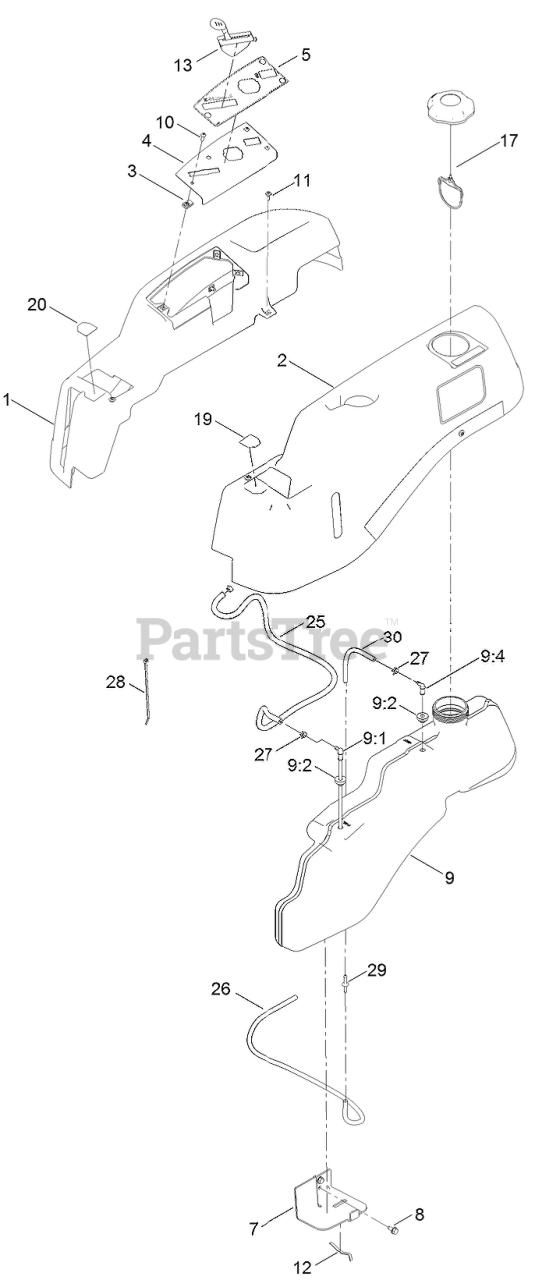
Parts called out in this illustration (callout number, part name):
1	POD-RH
4	PLATE-CONTROL
5	DECAL-PANEL, CONTROL
7	SUPPORT-TANK, FRONT
8	SCREW-HWHTF
9	FUEL TANK ASM
9:1	CONNECTOR-ELBOW, 90 DEG
9:2	BUSHING
9:4	FITTING-PLASTIC
10	SCREW-PRH
11	SCREW-SHOULDER
12	SPRING
13	CABLE-THROTTLE AND CHOKE
17	CAP-FUEL, RATCHETING
19	DECAL-LEVER, CONTROL (LH)
20	DECAL-LEVER, CONTROL (RH)
25	HOSE-FUEL
26	HOSE-FUEL
27	CLAMP-HOSE
28	TIE-CABLE
29	ADAPTOR-ORIFICE
30	HOSE-FUEL
